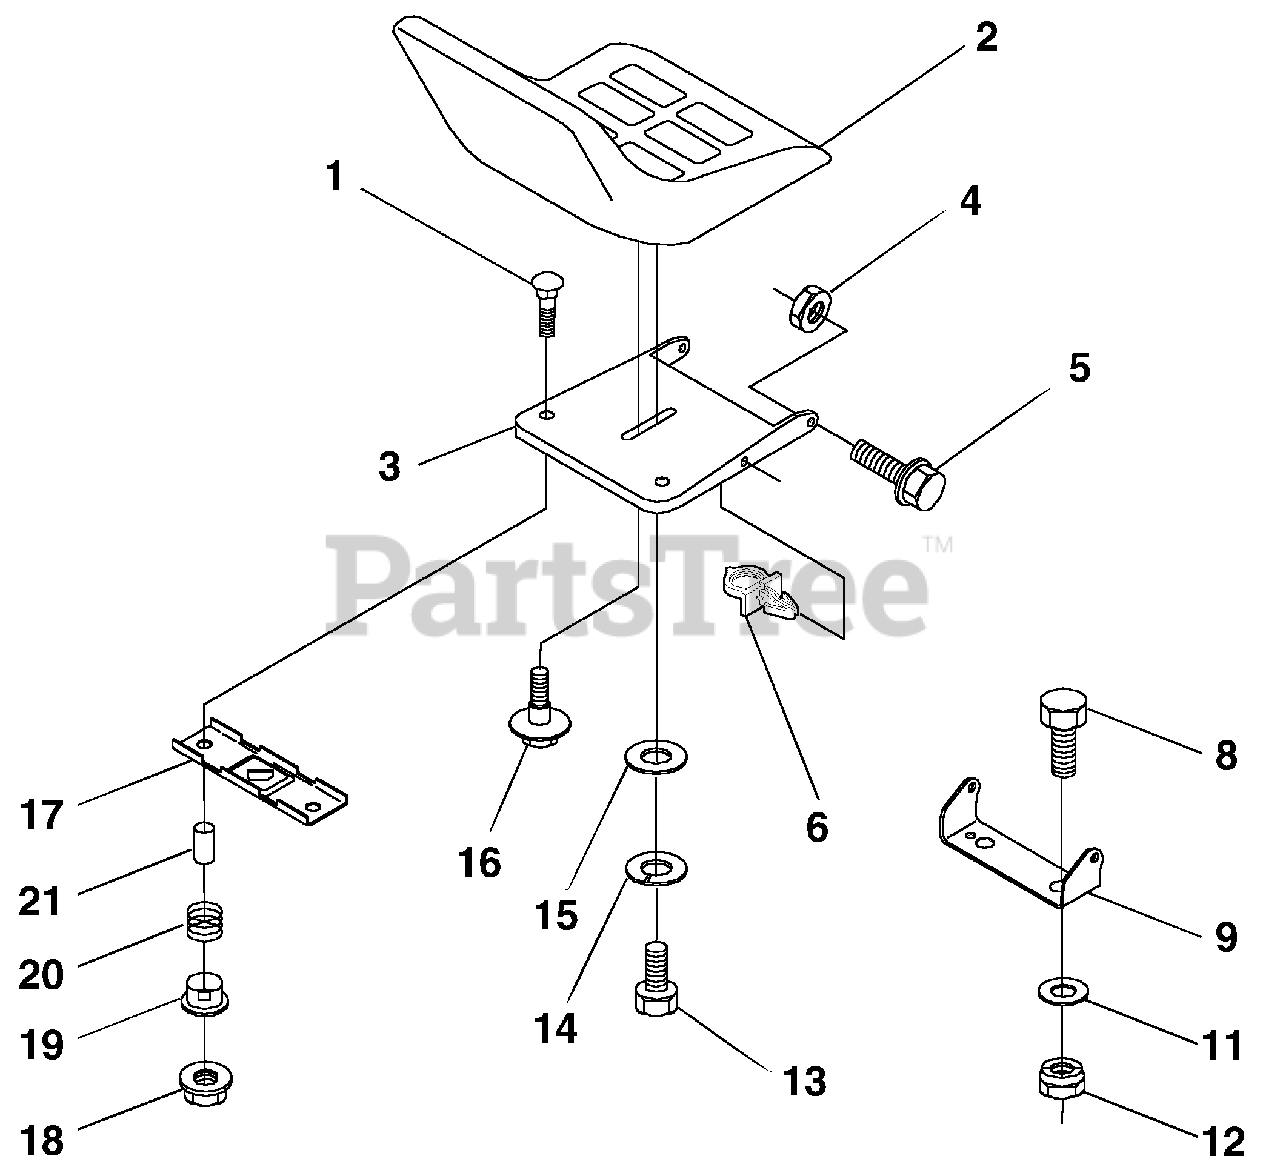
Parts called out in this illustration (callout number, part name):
1	Bolt, Carriage 1/4-20 x 1-1/2
2	Seat
3	Pan, Seat
4	Locknut, Hex w/Ins 5/16-18
5	Bolt, Shoulder 5/16-18 UNC
6	Clip, Push-in
8	Bolt, Fin Hex 3/8-16 UNC x 1
9	Bracket, Pivot Seat
11	Washer 12/32 x 2 x 10 Ga.
12	Nut, Lock Hex w/Wsh 3/8-16
13	Bolt Hex 1/2-13 x 7/8
14	Washer Lock Hvy. Hlicl Spring 1/2
15	Washer, 17/32 x 1-3/16 x 12 Ga.
16	Bolt, Shoulder
17	Bracket, Switch, Mounting
18	Nut, Hex Large Flange Lock
19	Bushing, Snap
20	Spring, Compression
21	Spacer, Split 28 Id. x .88 Lg.
